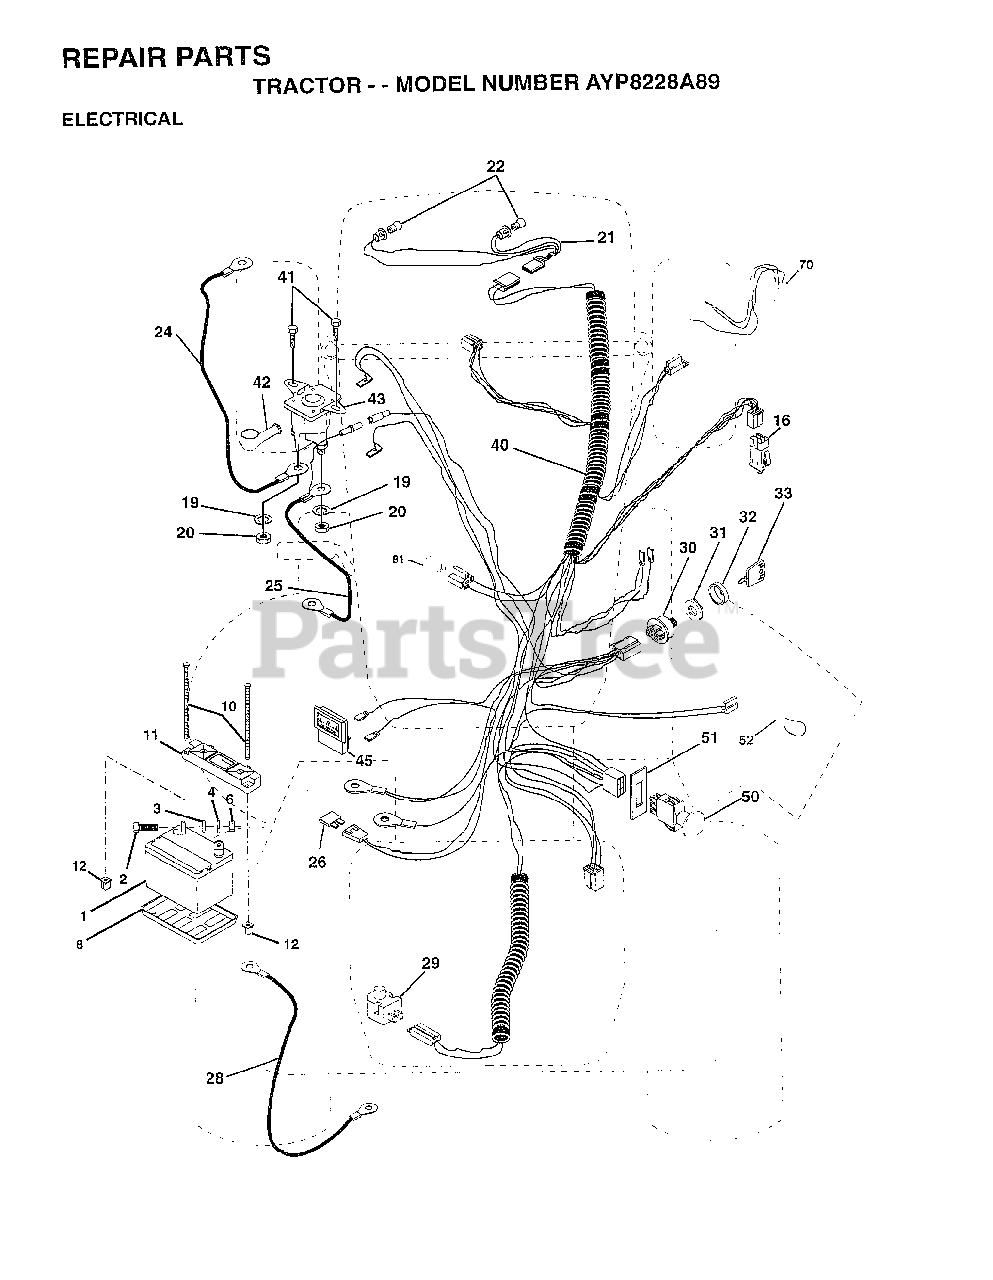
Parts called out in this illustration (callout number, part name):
2	BOLT LT
3	LOCKWASHER
4	WASHER
8	"TRAY T, BATTERY"
11	HOLDDOWN BATTERY
16	SWITCH INTERLOCK
20	NUT
21	"HARNESS,LIGHT SOC"
22	HEADLAMP BULB
24	CABLE-BATTERY T
25	CABLE.6GA.12.5.
26	FUSE HYT
28	CABLE T
29	SWITCH.PLUNGER
30	SWITCH IGN 4POS
31	NUT IGNITION
32	COVER KEY SWITCH
33	KEY
40	HARNESS.IGNITON
41	SCREW
45	AMMETER
50	PTO SWITCH.BLK
51	RING RETAIN PTO
52	PROTECTION LOOP
70	HARNESS.ENG.B&S
81	RELAY ASSY T
